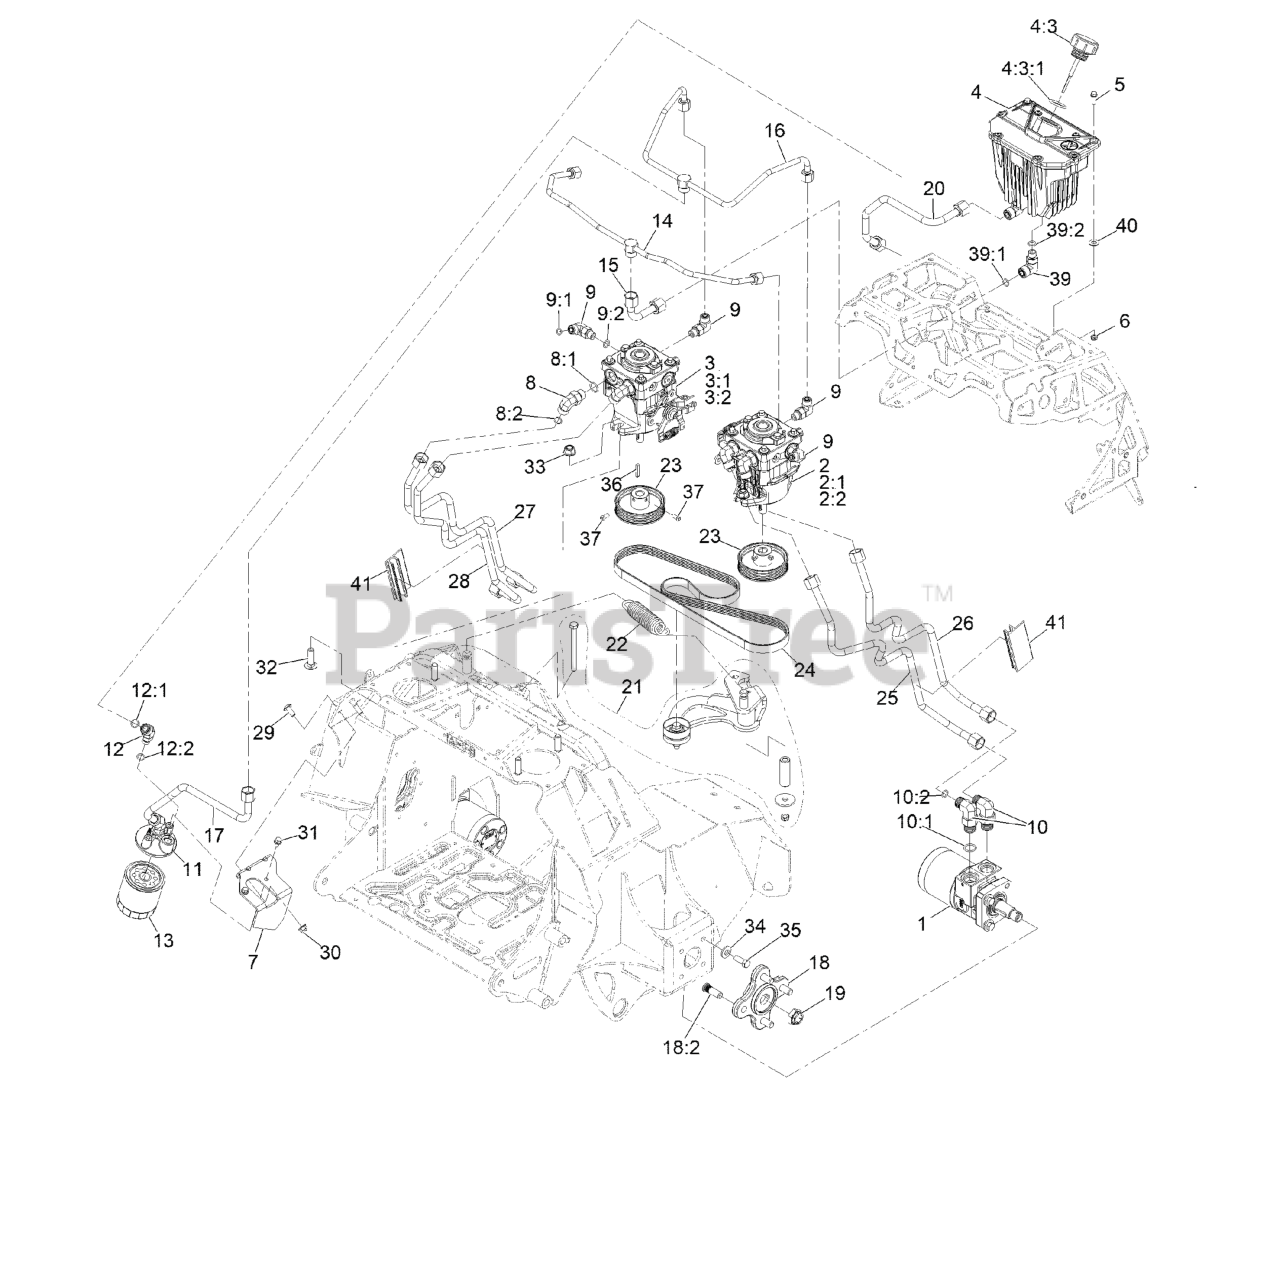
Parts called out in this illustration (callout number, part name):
1	MOTOR-WHEEL
2	PUMP-HYDRAULIC 10CC
2:1	KIT, 10CC/12CC PUMP KIT
2:2	SEAL OVERHAUL KIT
3	PUMP-HYDRAULIC 10CC
3:1	KIT, 10CC/12CC PUMP KIT
3:2	SEAL OVERHAUL KIT
4	ASM, HYDRAULIC RESERVOIR
4:3	Cap, Hydraulic
5	SCREW-HWH
6	NUT-LOCK, NI
7	MOUNT, FILTER
8	FITTING-ELBOW, 90 DEG
8:1	O-RING
8:2	O-RING
9	FITTING-ELBOW, 90 DEG
9:1	O-RING
9:2	O-RING
10	FITTING-ELBOW, 90 DEG
10:1	O-RING
10:2	O-RING
11	HEAD-FILTER
12	Adapter
12:1	O-RING
12:2	O-RING
13	FILTER-25 MICRON, BI-DIRECTIONAL
14	LINE, HYDRAULIC, CASE TEE
15	LINE, HYDRAULIC, CASE
16	LINE, HYDRAULIC, CHARGE TEE
17	LINE, HYD. CHARGE
18	ASM-HUB AND STUDS
18:2	STUD-WHEEL
19	NUT-LOCK
20	LINE, HYD. SUPPLY
21	ASM, IDLER ARM
22	SPRING, EXTENSION
24	BELT, PVK5
25	KIT-STE HYD LINE LT REAR B-A
26	KIT-STE HYD LINE LT FRNT A-B
27	KIT-STE HYD LINE RT REAR B-B
28	KIT-STE HYD LINE RT FRNT A-A
29	SCREW-TORX
30	NUT-HF, NI
31	SCREW-HHF
32	BOLT-CARR
33	NUT-HF, NI
34	WASHER-BELLEVILLE
35	SCREW-HH
36	KEY, 5MM X 5MM X 29MM
37	Screw-SQH
39	Fitting-HYD, 90 DEG
39:1	O-RING
39:2	O-RING
40	Washer-Thrust
41	SPACER-HYDRAULIC TUBE
